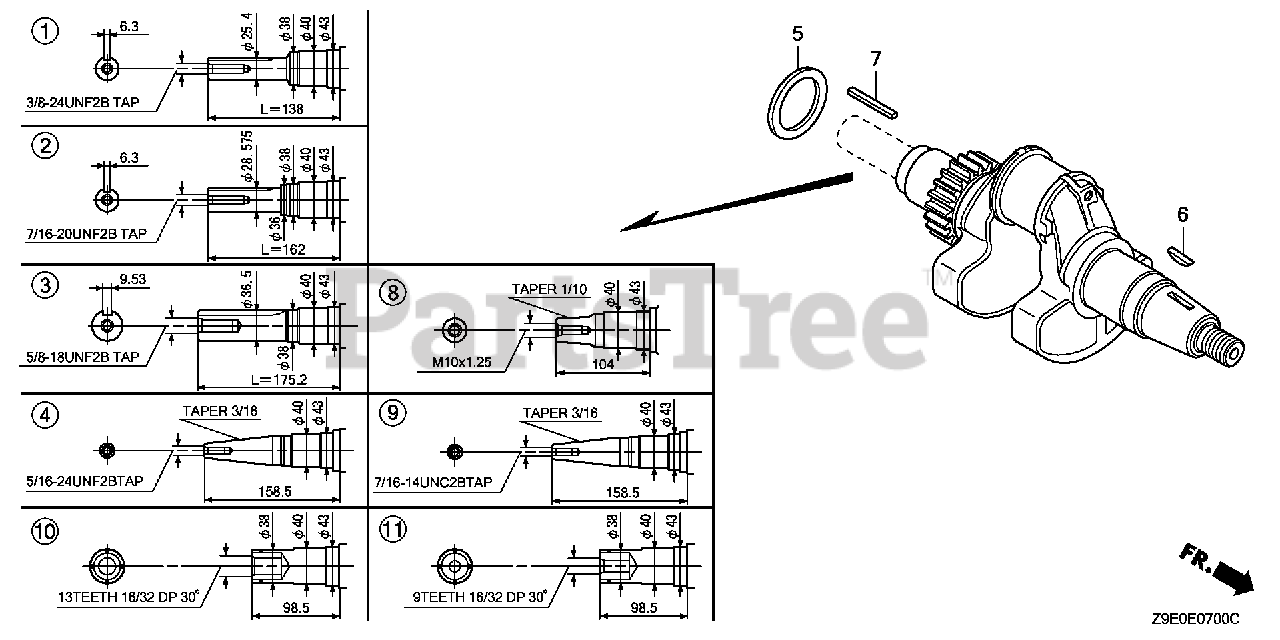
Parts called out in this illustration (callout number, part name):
5	WASHER, CRANKSHAFT THRUST
6	KEY, SPECIAL WOODRUFF (25X18)
10	CRANKSHAFT
